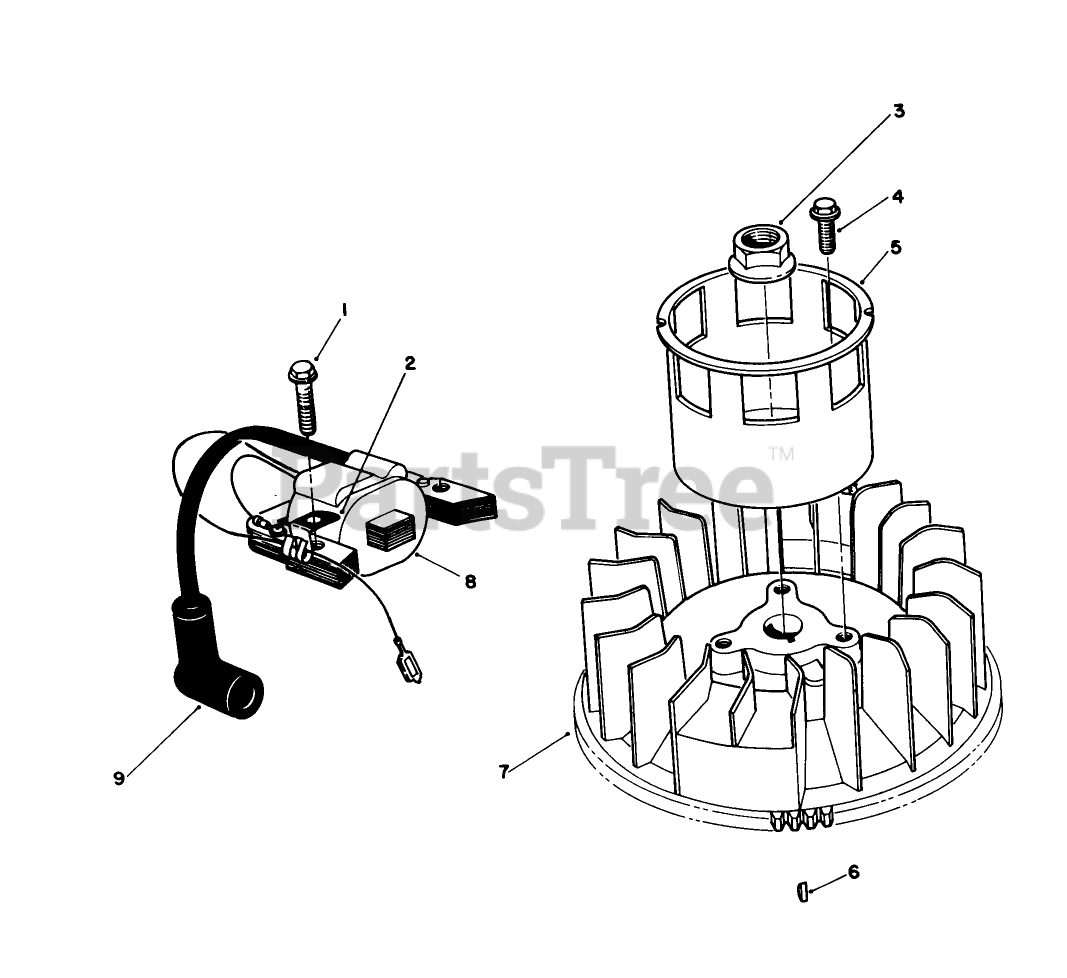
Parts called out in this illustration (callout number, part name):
2	CLAMP
7	FLYWHEEL
8	COIL ASM
9	COVER
